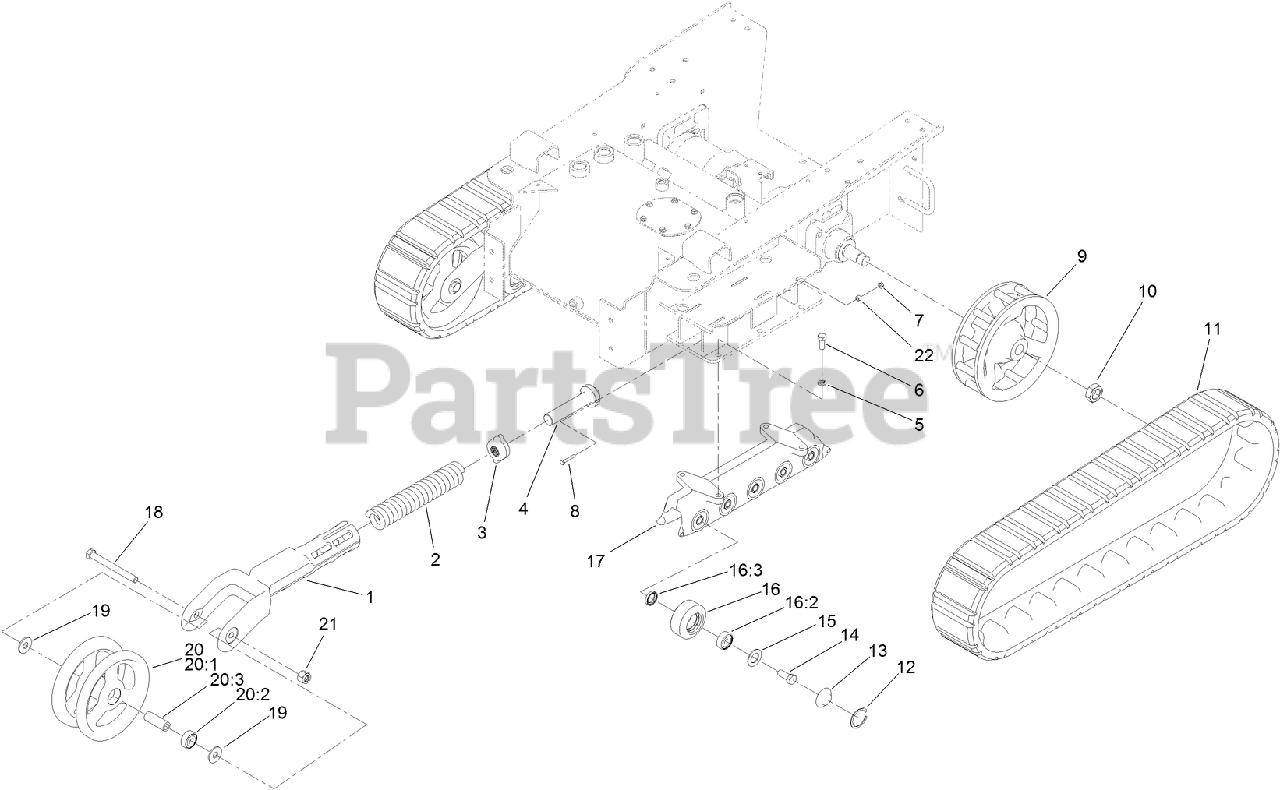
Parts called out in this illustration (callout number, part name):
1	ARM-TENSIONER
2	SPRING-COMPRESSION
3	BLOCK-TENSIONER
4	BOLT-TENSIONER
5	WASHER-LOCK
6	SCREW-HH
7	NUT-HHF
8	SCREW-HH
9	WHEEL-DRIVE
10	NUT-HEX
11	TRACK
12	RING-SNAP, INTERNAL
13	CAP-WHEEL, BEARING
14	SCREW-HH
15	Gasket-Bogie
16	Road Wheel ASM
16:2	BEARING-BALL
16:3	SEAL-OIL
17	GUIDE-TRACK
18	SCREW-HH
19	WASHER-FLAT
20	TENSIONER WHEEL ASM
20:1	WHEEL-TENSIONER
20:2	SPACER-WHEEL, TENSIONER
20:3	BEARING-BALL
21	NUT-HEX
22	SPACER
